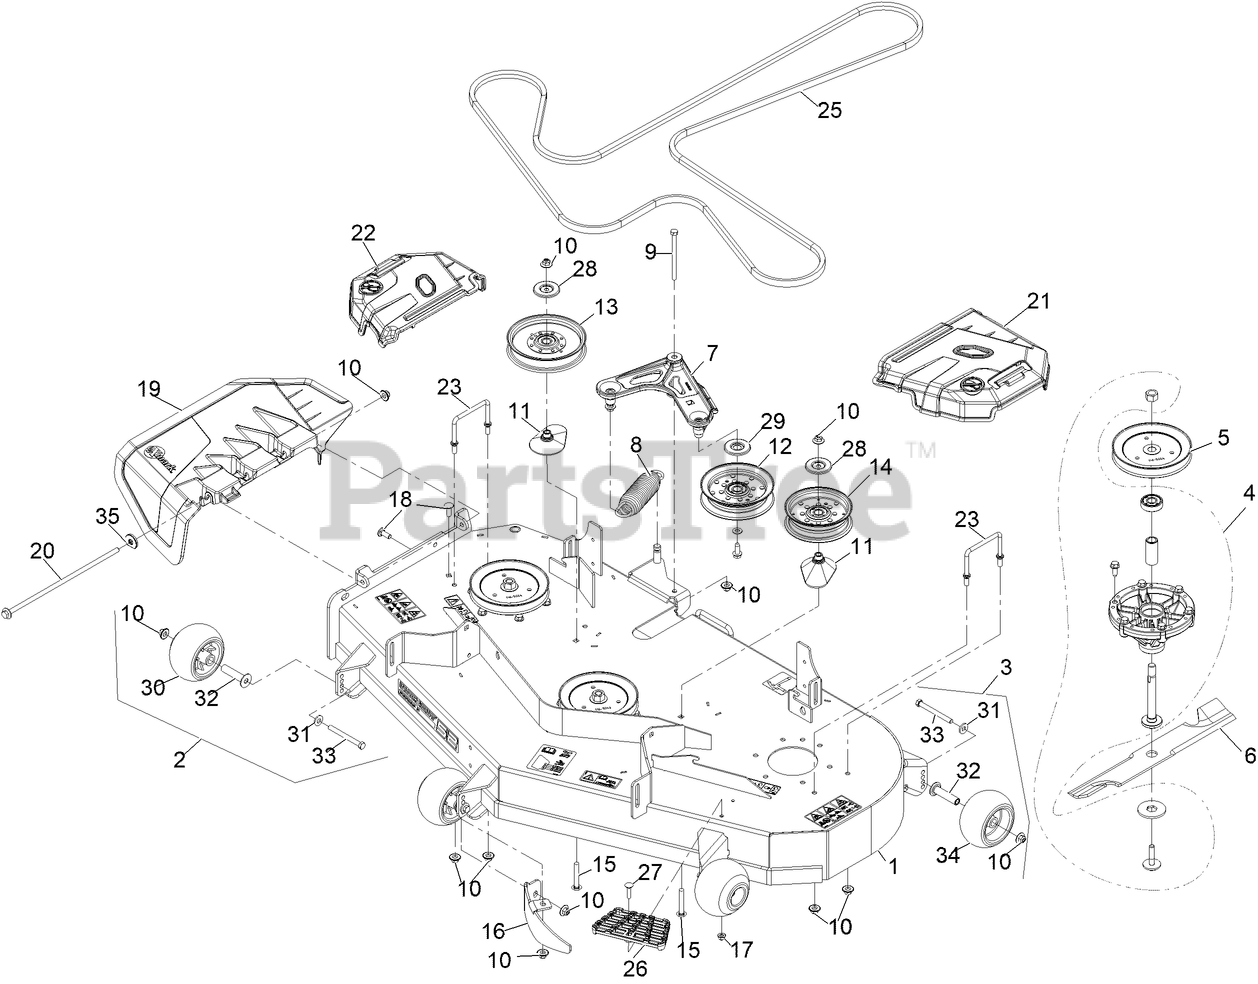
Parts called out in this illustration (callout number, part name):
1	ASM-DECK W/DECALS 523
2	KIT, ANTI-SCALP ROLLER
3	KIT-ANTISCALP ROLLER
4	ASM, CUTTER HOUSING COMPLETE
5	SHEAVE,BLADE DRIVE 6.50
7	ASM-IDLER ARM W/BEARINGS
8	SPRING-EXTENSION
9	SCREW-HH
10	Nut-Nyloc 3/8-16 Flg
11	SPACER-PULLEY
12	IDLER-PULLEY, FLAT
13	IDLER-PULLEY, FLAT 6.00X1.00
14	IDLER-PULLEY, FLAT 5.00X1
15	SCREW-CARR
16	BAFFLE-DOGLEG, LZE-PNS-52
17	NUT-HF, NI
18	SCREW-CARR
19	Chute-Deck Discharge
20	Pin, Chute
21	SHIELD, LT
22	SHIELD, RT
23	WIREFORM-COVER
26	STEP-DECK
27	Bolt-Carriage 5/16-18 X 1 1/4
28	SHIELD-DUST
29	SHIELD-GUARD, DUST
30	ROLLER-SCALP, ANTI
31	WASHER-BELLEVILLE
32	AXLE, ROLLER
33	SCREW-HH 3/8-16 X 3 3/4 GR 8
34	ROLLER-SCALP, ANTI
35	Retainer, Chute
